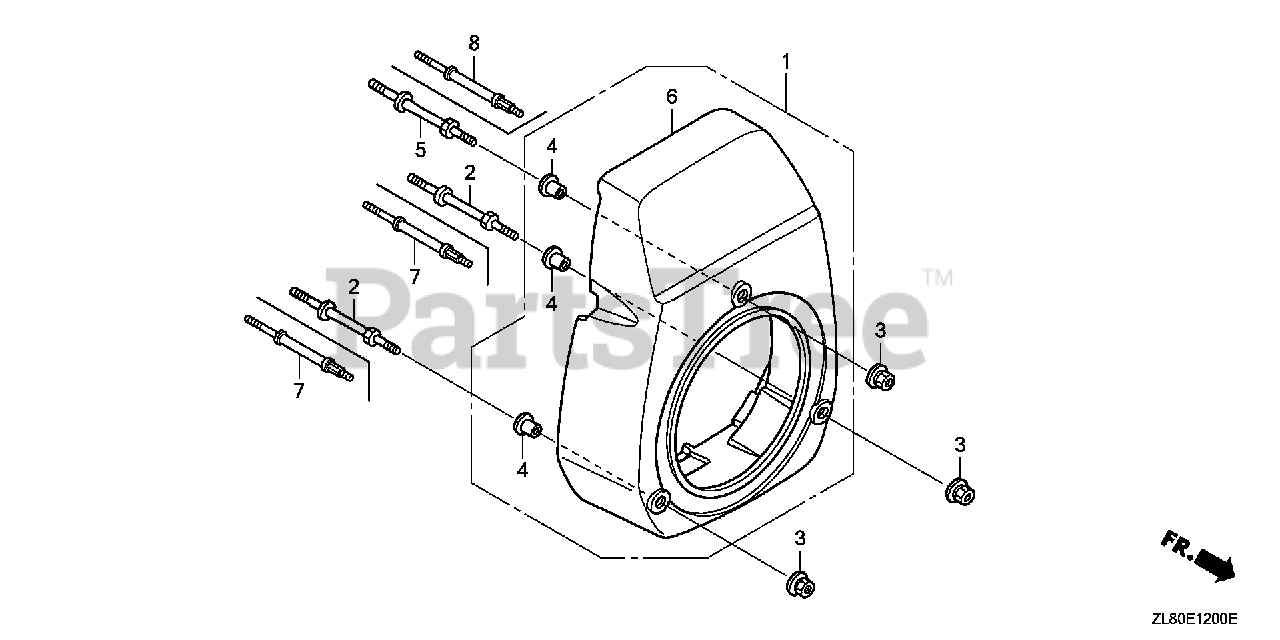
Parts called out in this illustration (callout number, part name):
1	COVER, FAN *NH1* (BLACK)
1	COVER, FAN *R280* (POWER RED)
2	BOLT, STUD
3	NUT, FLANGE (6MM)
4	COLLAR, FAN COVER (Honda Code 5580527). (N/A: SEE ASSEMBLY)
5	BOLT, STUD
